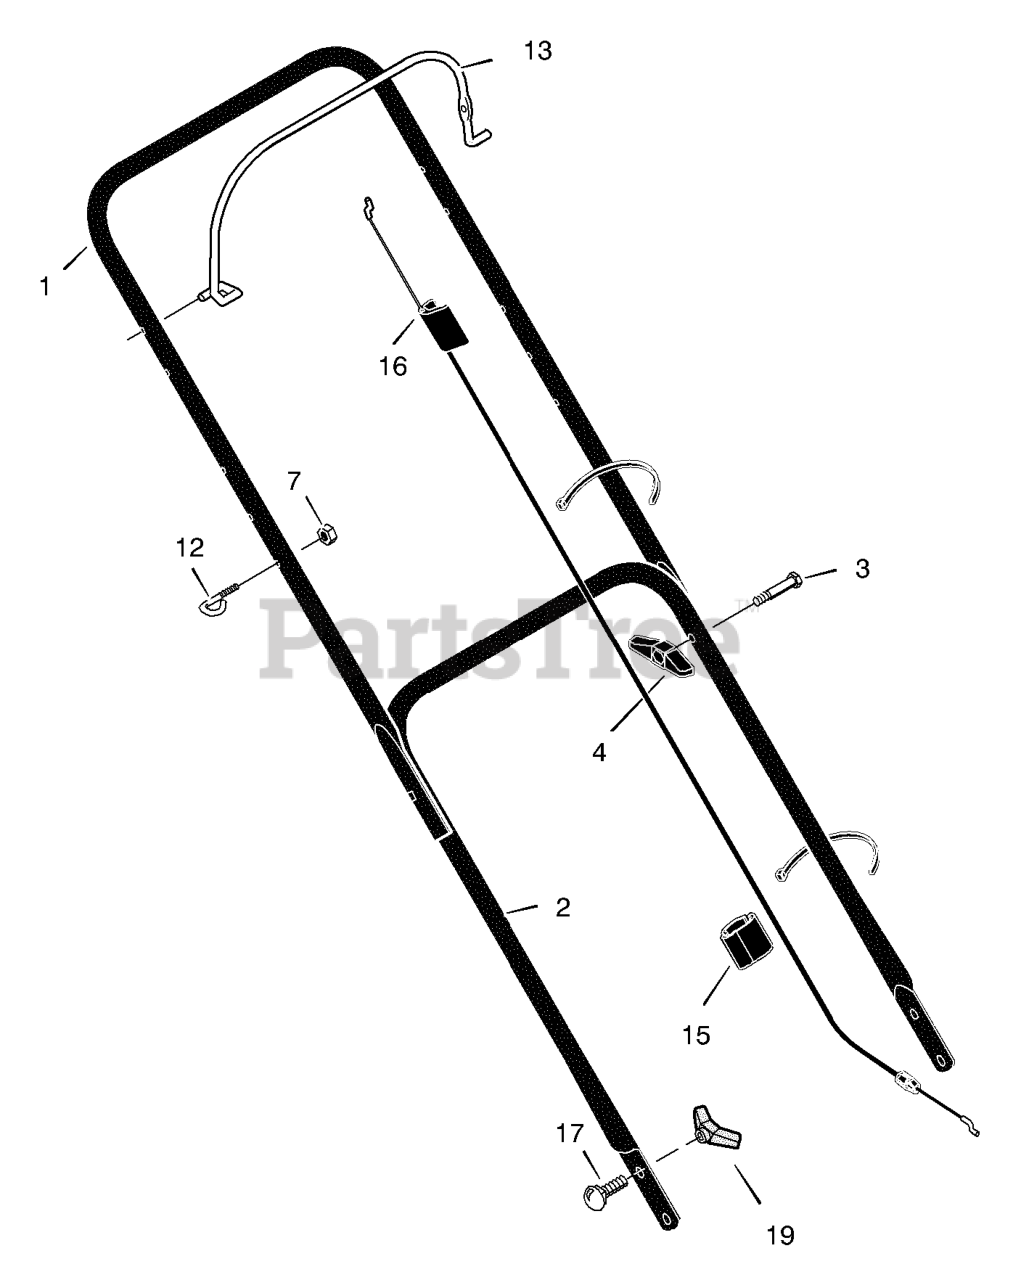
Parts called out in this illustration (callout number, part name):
1	Handle, Upper (Black)
2	Handle, Lower (Black)
4	Knob, Plastic
7	Locknut
12	Guide, Rope
13	Lever, Engine Stop
15	Clip, Cable
16	Engine Stop Cable
17	Bolt, Carriage
19	Knob, Plastic
